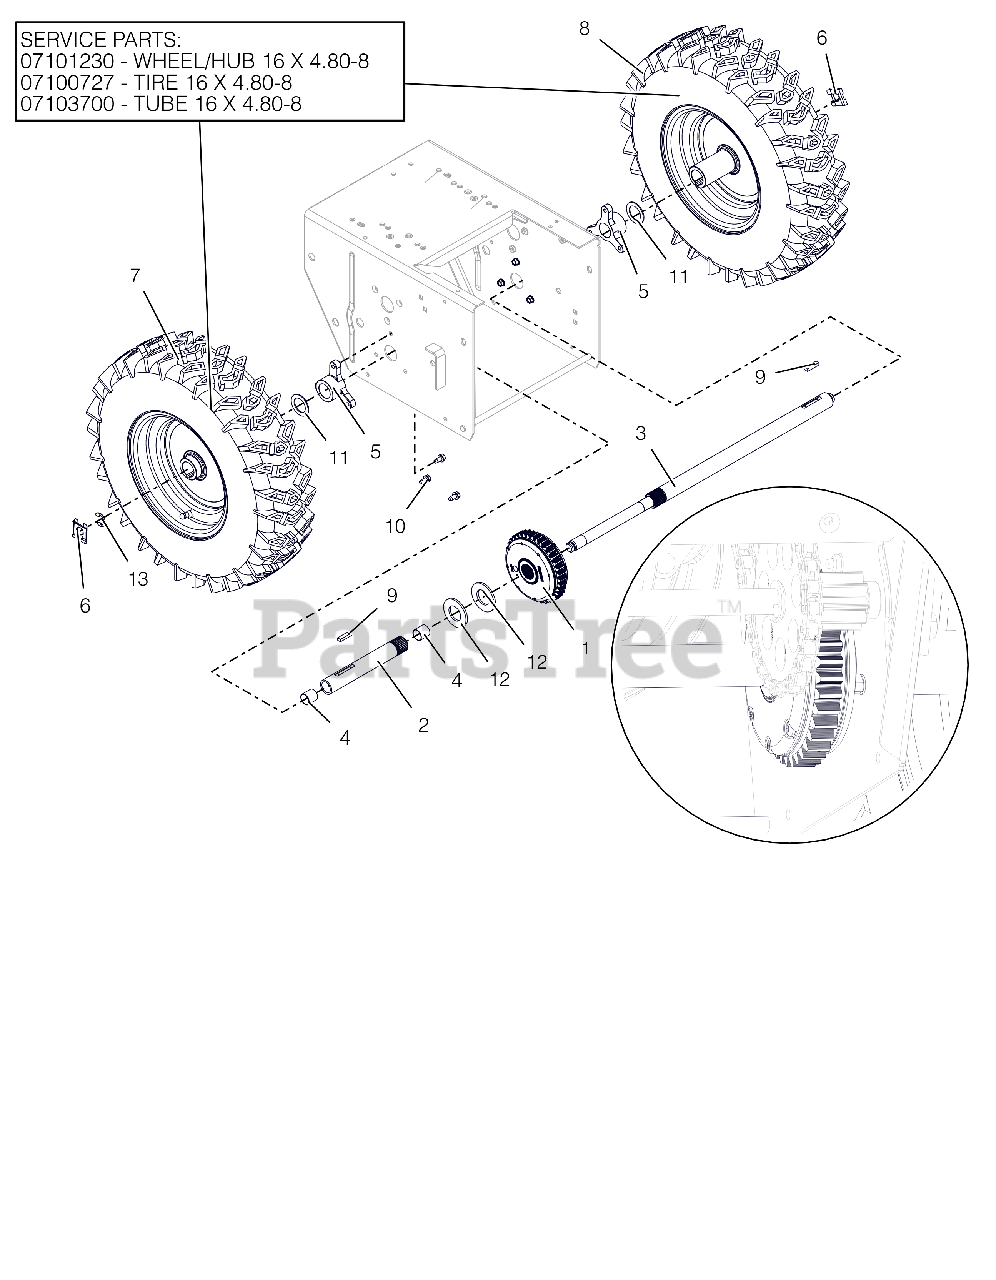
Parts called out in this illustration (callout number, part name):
1	DIFFERENTIAL, AUTOMATIC
2	AXLE, SHORT - W/BUSHINGS
3	AXLE,LONG-DELUXE AUTO DIFF
4	BSHG-SLV .706X.764X.75 BRZ
5	BUSHING, AXLE
6	CLIP, SNAP .625 DIA
7	TIRE/WHEEL,RH 16X4.8-8 DIFF T2
8	TIRE/WHEEL,LH 16X4.8-8 DIFF T2
9	KEY-RECT .25X.188X1.00
10	SCR-TAP .25-20X.50 HWH TR YWZ
11	WSHR-FL-STL 1.010X1.505X.062YZ
12	WSHR-FL-STL- 1.062X2.0X.134 YZ
13	RG-RTNG-EXT .625X.042
14	HUB, WHEEL-16X4.8-8
15	TIRE, 4.80-8 K478
16	TUBE
